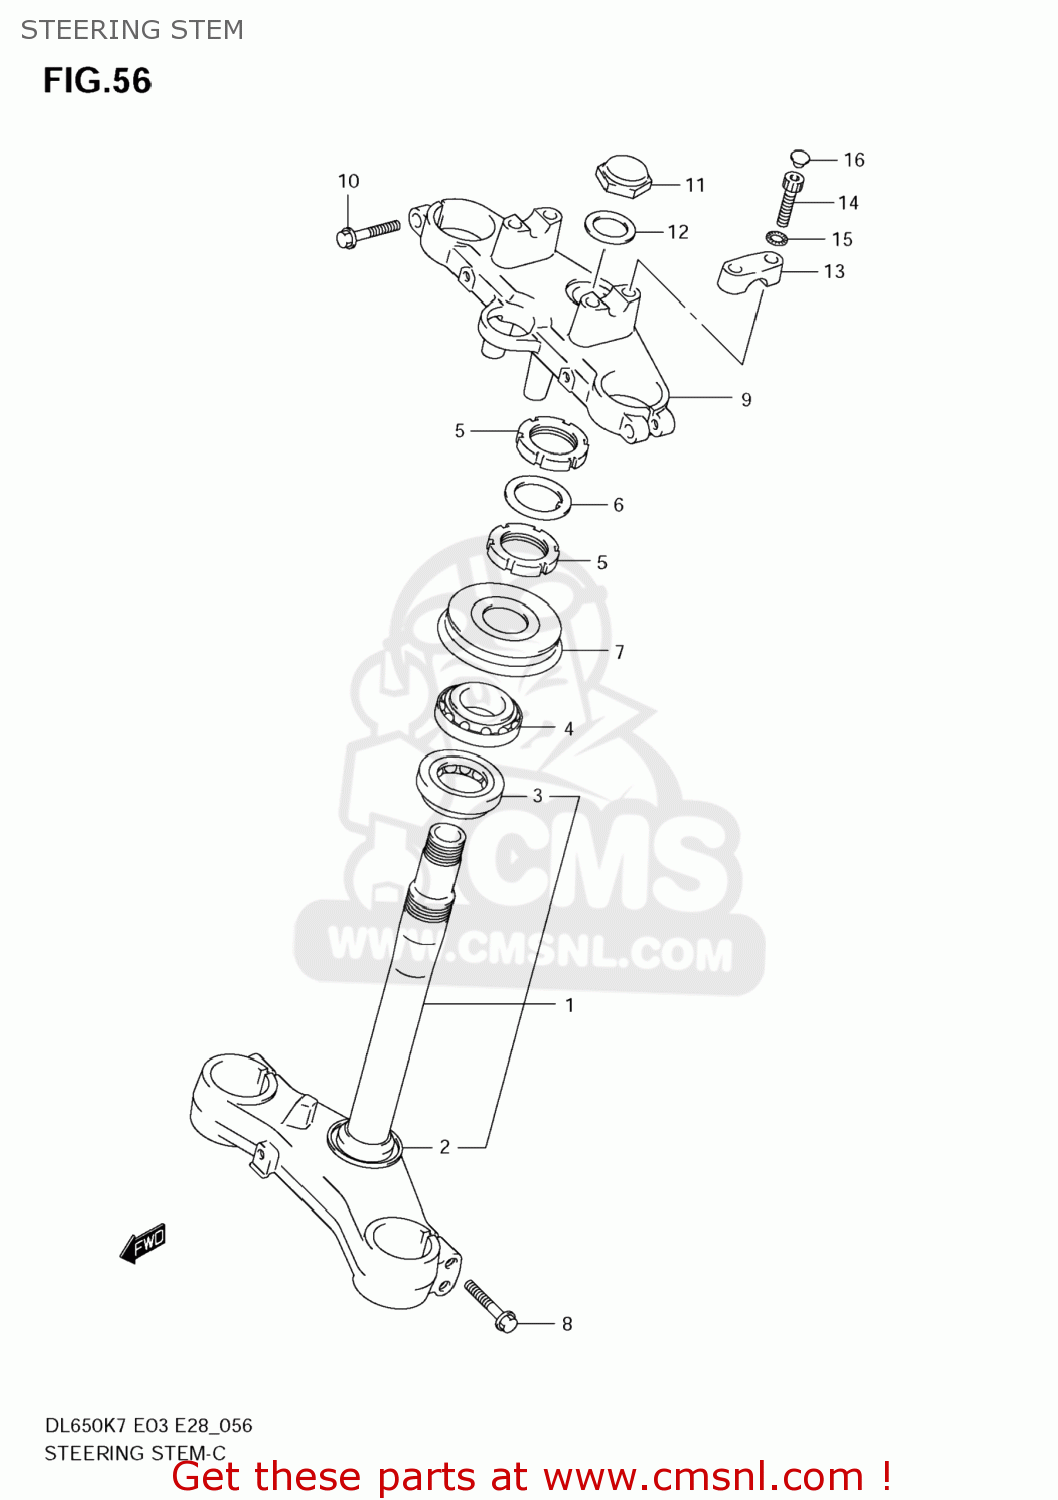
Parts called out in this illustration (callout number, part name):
1	STEM,STEERING
2	SEAL,STEERING LWR
3	BEARING(30X55X17)
4	BEARING(30X55X17)
5	NUT,STEERING STEM
6	WASHER,STEERING STEM
7	SEAL,STEERING UPR DUST
8	BOLT
9	HEAD,STEERING STEM
10	BOLT
11	NUT
12	WASHER
13	HOLDER,HANDLE UPR
14	BOLT
15	WASHER
16	CAP(OD:11)
